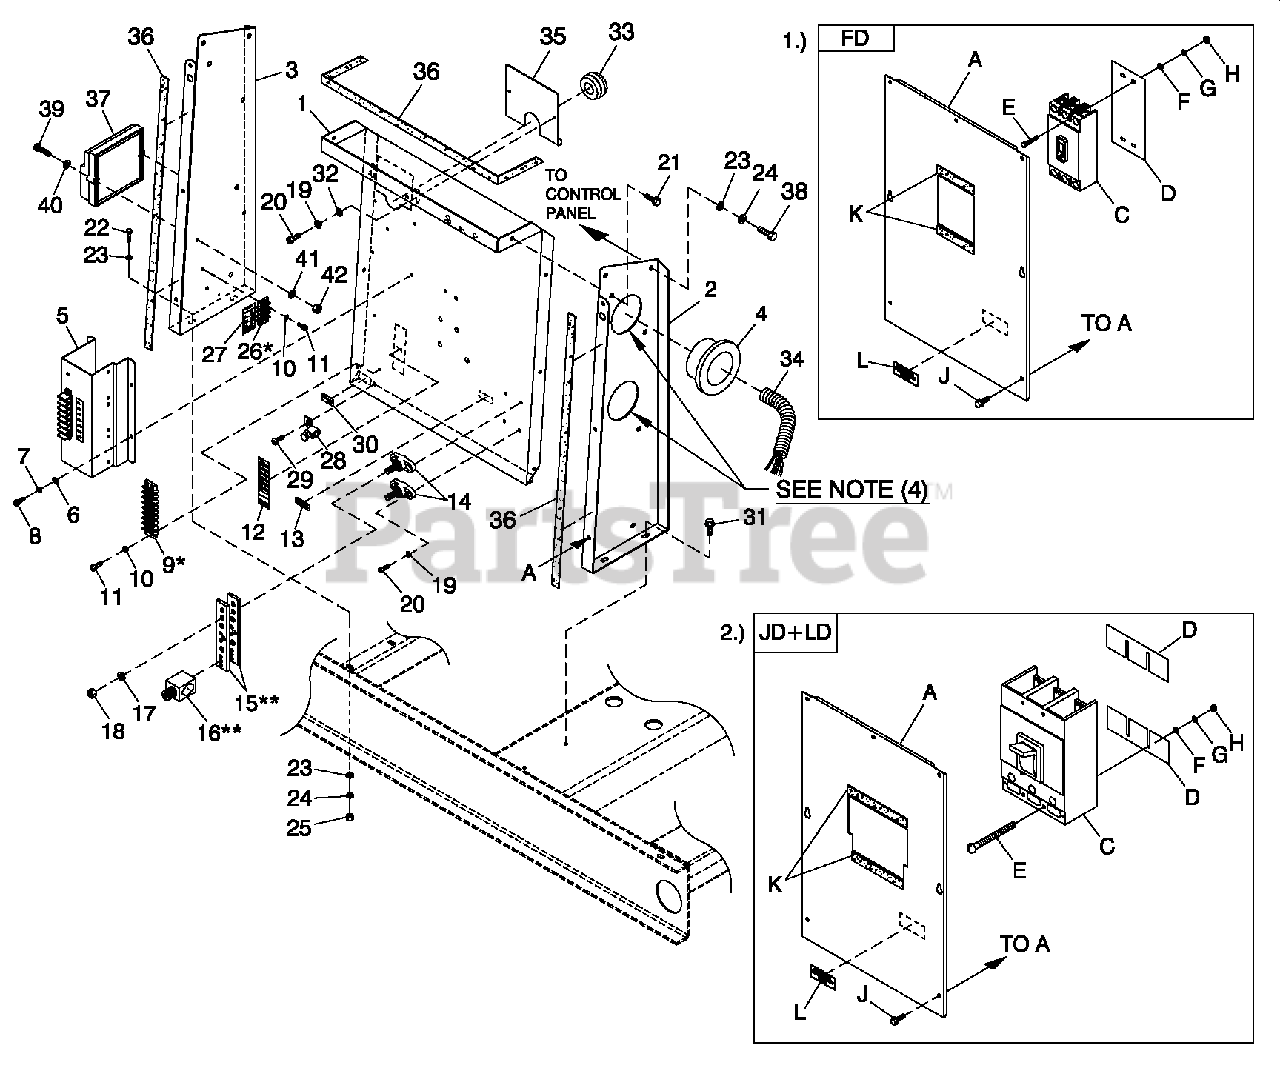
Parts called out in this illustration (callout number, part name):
1	PANEL CB CONN BOX
2	STAND RH CONTROL
2	UL CIRCUIT BREAKER (FD)
2	UL CIRCUIT BREAKER (JD+LD)
3	STAND LH CONTROL C5 GRBX
4	BUSHING SNAP SB-2.5-31
5	INTERFACE 1PH 240V
6	WASHER FLAT M4
7	WASHER LOC K#8-M4
8	SCREW PHTT M4-0.7 X 10ZYC
9	BLOC K TERM 20A 8 X 6 X 1100V
10	WASHER LOC K#6
11	SCREW PHTT #6-32 X 1/2 ZYC
12	DECAL CPL CUST CONN H CTRL
13	DECAL NEUTRAL
14	JUNCTION BLOC K 3/8-16
15	BUS BAR NEUTRAL BLOC K 390
16	LUG SLD LSS 600/250-1/0 X 1/4-28
17	WASHER LOCK 3/8
18	NUT HEX 3/8-16 STEEL
19	WASHER LOCK M5
20	SCREW PHTT M5-0.8X 16 ZYC
21	SCREW THF M6-1 X 16 N WA Z/JS
22	SCREW HHCM6-1.0X 20 G8.8
23	WASHER FLAT 1/4-M6 ZINC
24	WASHER LOCK M6-1/4
25	NUT H E X M 6 X 1.0G8YELCH R
26	BLOCK TERM 2 0 A 6 X 3 X 1100V
27	DECAL CUST CONN 120V UTILITY
28	LUG SLD LSS #6-14X 13/64CU
29	SCREW HHTT #10-32X3/8 CZ
30	DECAL GROUND LUG
31	SCREW HHTT M6-1.0X16ZYC
32	WASHER FLAT M5
33	GROMMET 1.25 X .25 X .75
34	CONDUIT FLEX 2.0" ID
35	PLATE WIRE SNGLGALV
36	TAPE ELEC 1/2 FOAM (AS REQ’D)
37	A SSY PCB 4.6L IGNITION MODULE
38	SCREW HHC M6-1.0X 16G8.8
39	SCREW PPHM #10/32X2
40	WASHER FLAT #10 ZINC
41	WASHER LOCK #10
42	NUT HEX #10-32 STEEL
A	COVER FD FRM CB
C	CB 0150A 3P 600V S FD6 LL
D	INSULATOR CB FD FRAME 30MIL
E	SCREW SHC 1/4-20 X 4 G8.8 NZ
F	WASHER FLAT 1/4-M6 ZINC
G	WASHER LOCK M6-1/4
H	NUT HEX 1/4-20 STEEL
J	SCREW THF M6-1 X 16 N WA Z/JS
K	TAPE ELEC 1/2 FOAM (AS REQ’D)
L	DECAL CUSTOMER CONNECT INSIDE
A	COVER CIRBRKRJD/LD
C	CB0300A3P 600VS JD6LL
D	INSULATOR CIRCUIT BR. JD/LD
E	SCREW RHM 1/4-20X3
K	TAPE ELEC 1/2 FOAM (AS REQ'D)
